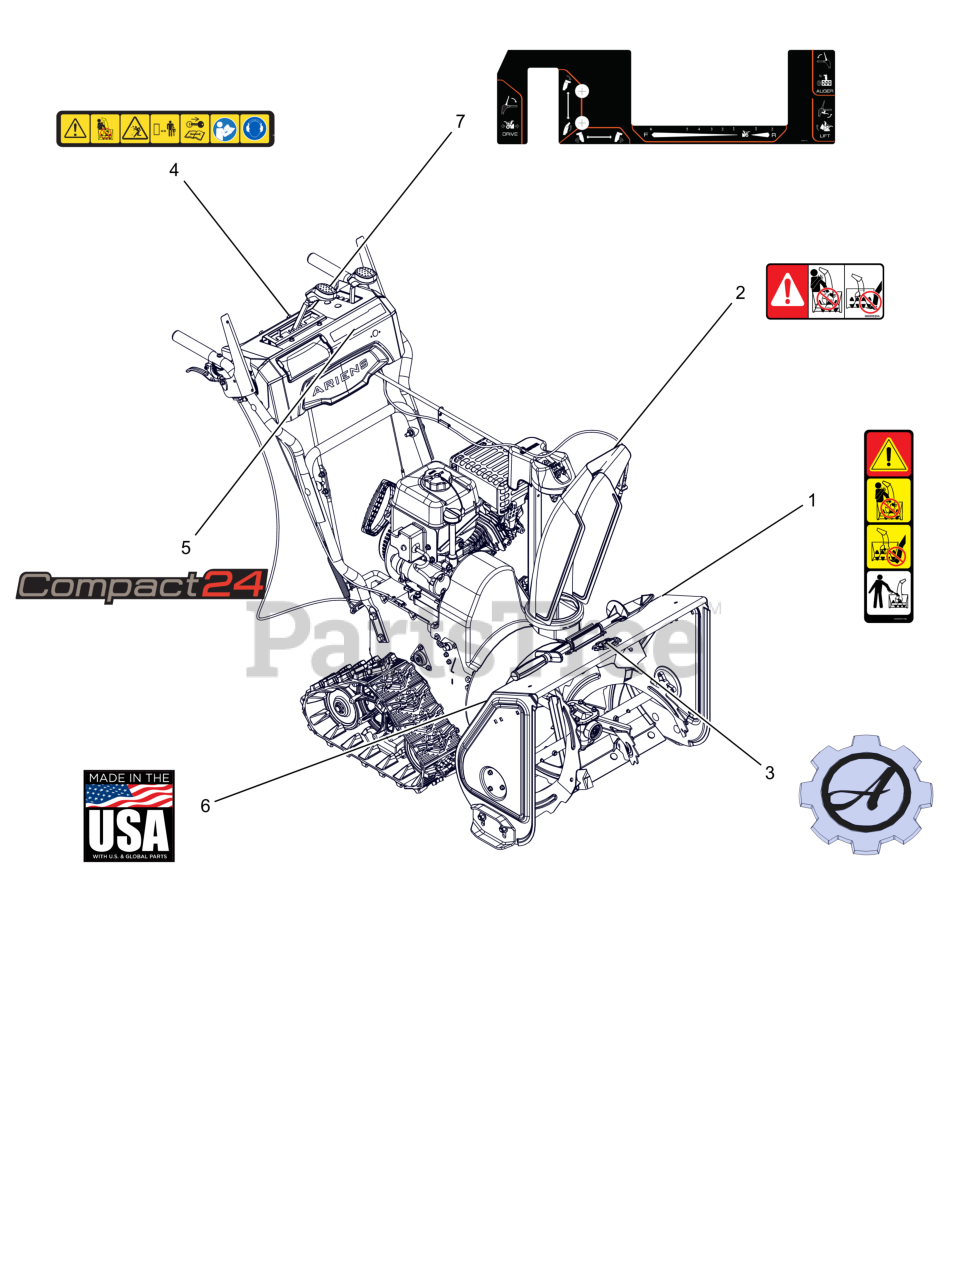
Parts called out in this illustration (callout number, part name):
1	DECAL, DANGER - ROTATING PARTS
2	DECAL, DANGER
3	DECAL, ARIENS - GEAR BADGE
4	DECAL,DASH - SAFETY
5	DECAL, DASH - COMPACT 24
6	DECAL, MADE IN USA
7	DECAL,CONTROL-COMP TRACK
